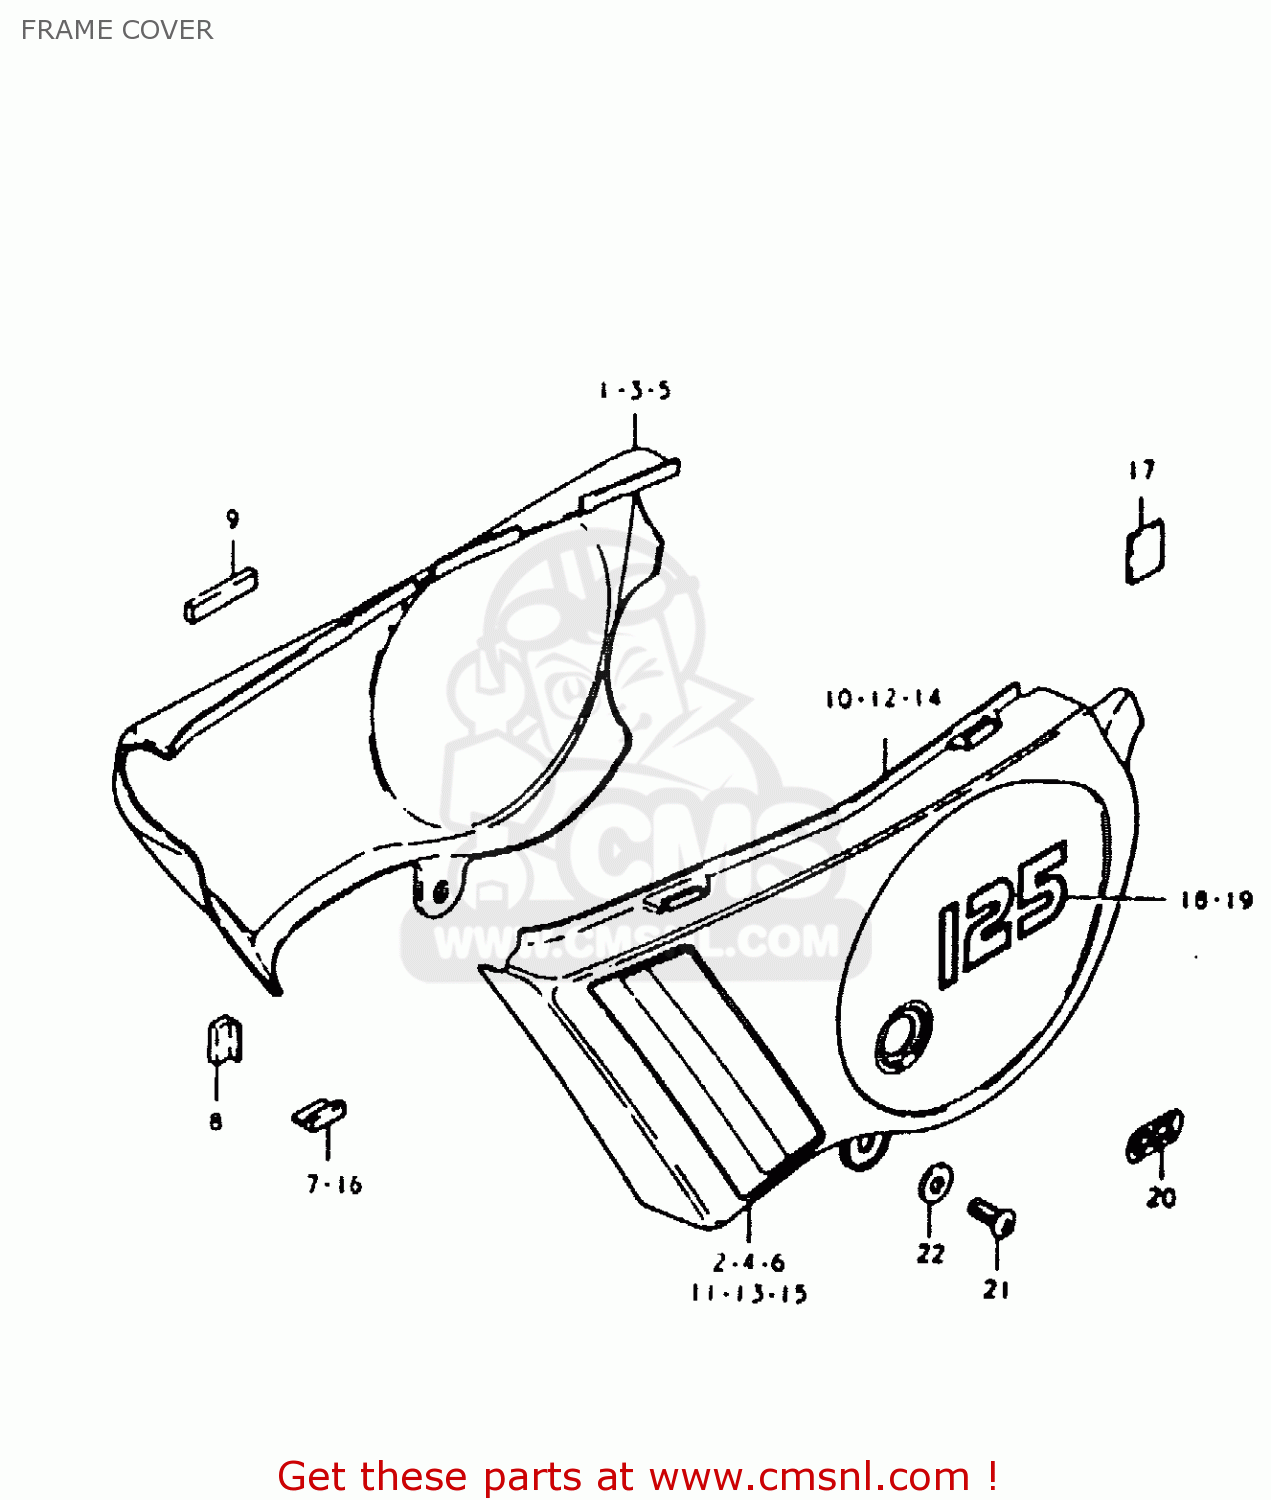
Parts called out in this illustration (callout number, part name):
1	COVER, FRAME RH (RED)
2	TAPE, RH
3	COVER,FRAME,RIGHT
4	TAPE, RH
5	COVER, FRAME RH (WHITE)
6	TAPE, RH
7	CUSHION,FRAME COVER
8	CUSHION,FRAME COVER
9	CUSHION,FRAME COVER
10	COVER, FRAME LH (RED)
11	TAPE, LH
12	COVER,FRAME,LEFT
13	TAPE, LH
14	COVER, FRAME LH (WHITE)
15	TAPE LH
16	CUSHION,FRAME COVER
17	PROTECTOR(170X95X3.0)
18	EMBLEM "125" RH
19	EMBLEM "125" LH
20	EMBLEM,CCIS
21	SCREW 6X12
22	WASHER
